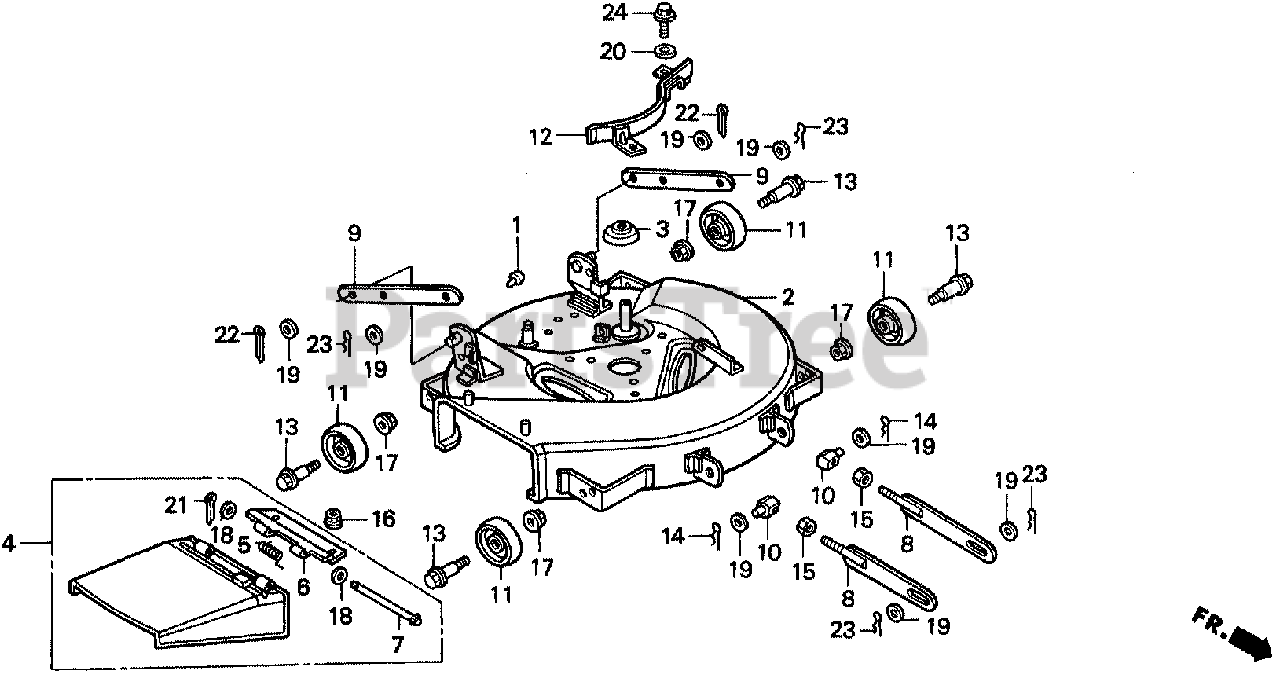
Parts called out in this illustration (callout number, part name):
1	RUBBER, STOPPER
2	HOUSING, CUTTER
3	CAP, TENSION ARM
4	ADAPTER, DISCHARGE *NH1* (BLACK)
5	SPRING, DISCHARGE ADAPTER
6	HINGE, DISCHARGE ADAPTER
7	PIN, DISCHARGE ADAPTER (NOT AVAILABLE)
8	LINK, FR. DECK
9	LINK, RR. DECK
10	PIN, FR. LINK ADJUSTING
11	ROLLER, ANTI-SCALP
12	COVER, DECK PULLEY
13	BOLT, ANTI-SCALP ROLLER
14	PIN, LOCK (14MM)
15	NUT, HEX. (12MM)
16	NUT, FLANGE (8MM)
17	NUT, FLANGE (10MM)
18	WASHER, PLAIN (6MM)
19	WASHER, PLAIN (14MM)
20	WASHER, PLAIN (6MM)
21	PIN, SPLIT (2.0X12)
22	PIN, COTTER (4X25)
23	PIN, LOCK (14MM)
24	BOLT, FLANGE (6X16)
